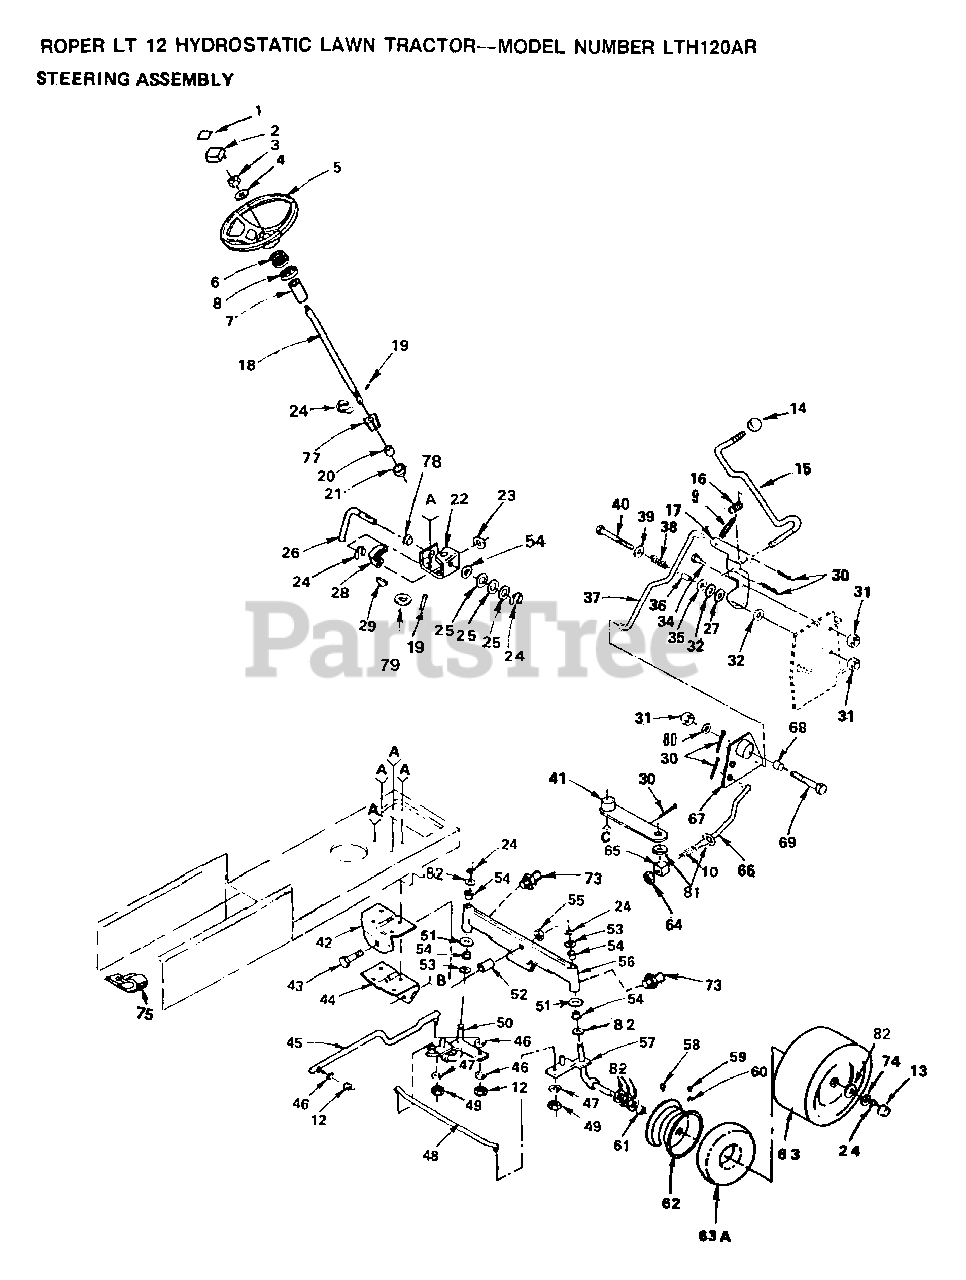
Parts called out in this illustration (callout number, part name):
1	DECAL - STEERING WHEEL
2	INSERT-WHEEL LT
3	NUT
4	WASHER
6	ADAPTER LT
9	SPRING.RETAINER
10	SPRING GTV
13	HUB CAP
14	KNOB T (1/2-HOLE)
15	ROD.YTH
17	BRKT CONTROL HYT
18	STEERING SHAFT T
20	SHAFT SPACER LT
21	BUSHING
23	WASHER D
24	RING
25	WASHER .T
26	ROD STEERING T
28	GEAR.SECTOR.HYT
29	KEY-WOODRUFF LT
30	COTTER PIN
32	WASHER FRIC HYT
34	BOLT HYT
35	WASHER D
36	SPACER HYT
37	LINK CONTROL HY
38	SPRING HYT
39	WASHER
40	BOLT - HEX 3/8 - 16 X 3
41	ARM ASSEM HYT
42	SUPPORT-SADDL T
43	BOLT LT
44	SUPPORT.SADDLE.FT
45	LINK-DRAG LT
46	LOCKWASHER
47	LOCKWASHER
49	NUT
50	SPINDLE LH YT
51	WASHER
52	BEARING
53	WASHER .T
54	COL. SRTG. BEAR.
55	"NUT-LOC,FLANGE LT"
56	FRONT AXLE
58	FITTING LT
59	VALVE STEM LT
60	VALVE CAP
61	"FLANGE, BEARING"
63A	TUBE.5.3/4.5/6
64	NUT
65	TRUNION HYT
67	"HYT, BELLCRANK"
73	ZERK M
75	INSUL CLIP T
77	GEAR PINION T
78	NYLINER T
79	NYLINER T
80	WASHER
81	WASHER T
